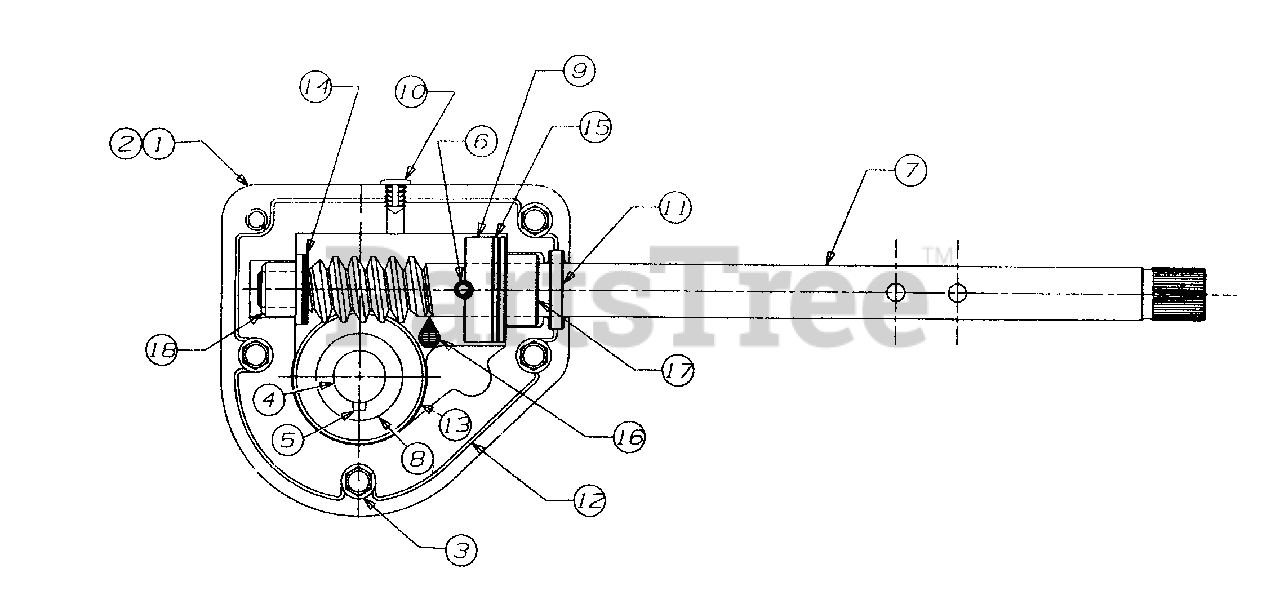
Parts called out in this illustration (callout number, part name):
1	Housing - L.H.
2	Housing - R.H.
3	Screw
4	Spiral Axle 24"
5	Key
6	Pin-Spiral
7	Shaft-Worm
8	Gear-Worm
9	Collar-Thrust
11	Seal-Oil
12	Locktite 5699
13	Washer-Flat
14	Washer-Flat
15	Washer-Flat
16	Grease, Sold By The Ounce
17	Bearing-Flange
18	Bearing-Flange
